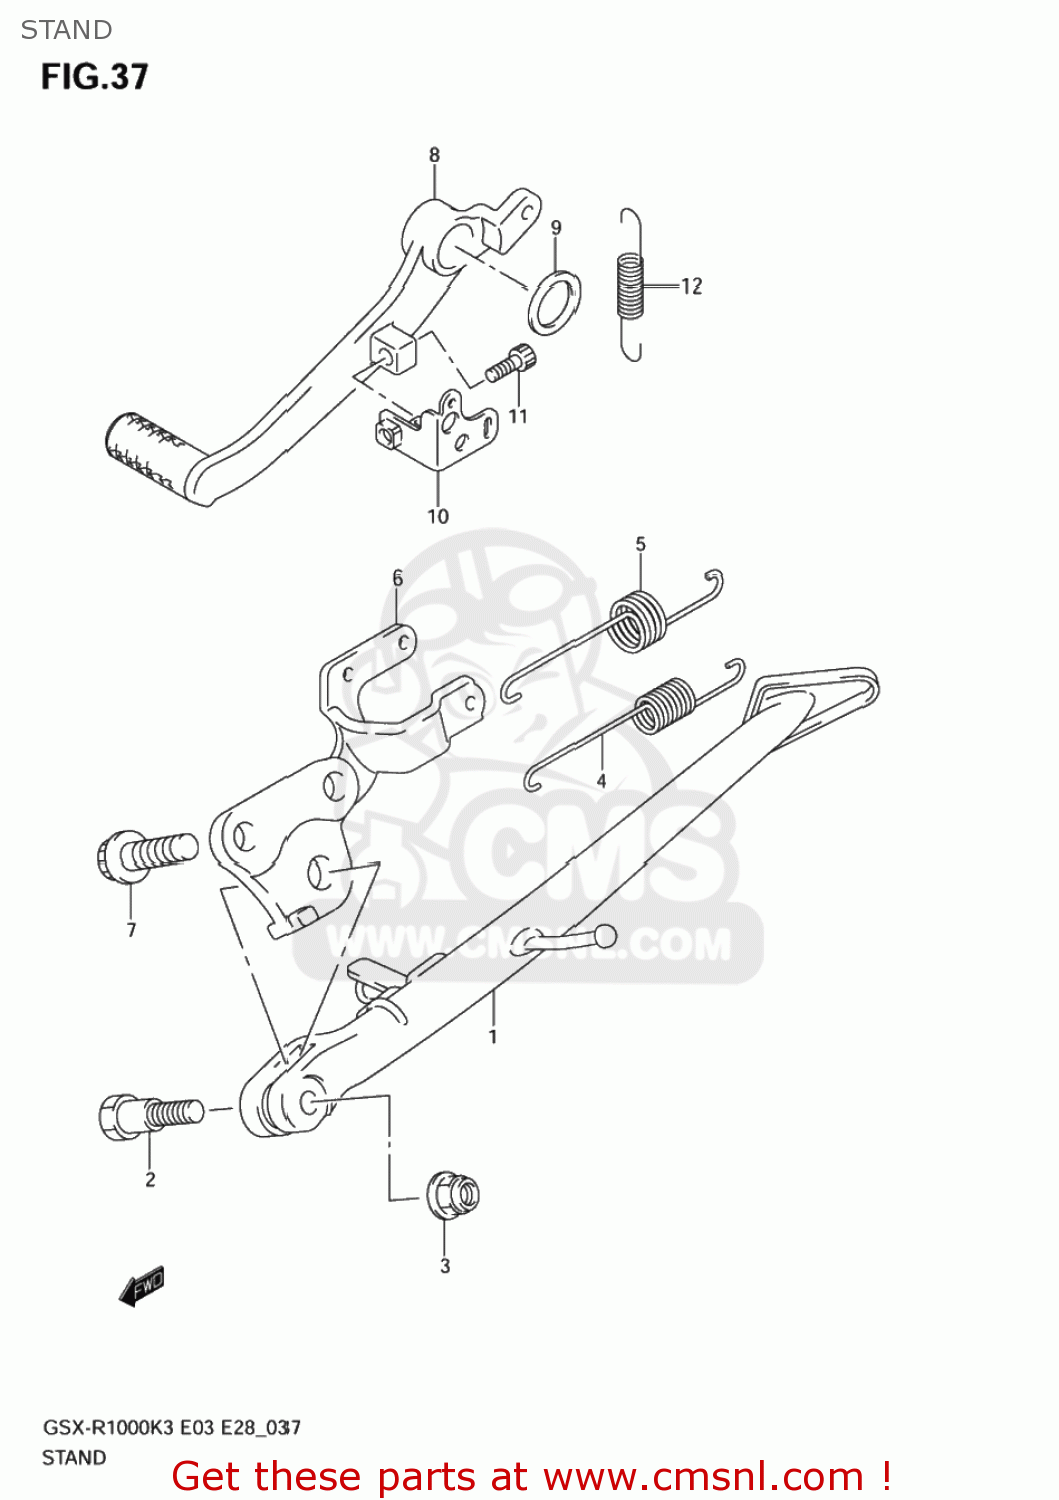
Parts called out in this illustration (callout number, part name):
1	STAND,PROP
2	BOLT(10X21)
3	NUT
4	SPRING
5	SPRING
6	BRACKET,PROP STAND
7	BOLT(10X28)
8	PEDAL,BRAKE
9	WASHER(18X24X1)
10	BRACKET,RETURN SPRING
11	BOLT,OIL FILLE
12	SPRING
